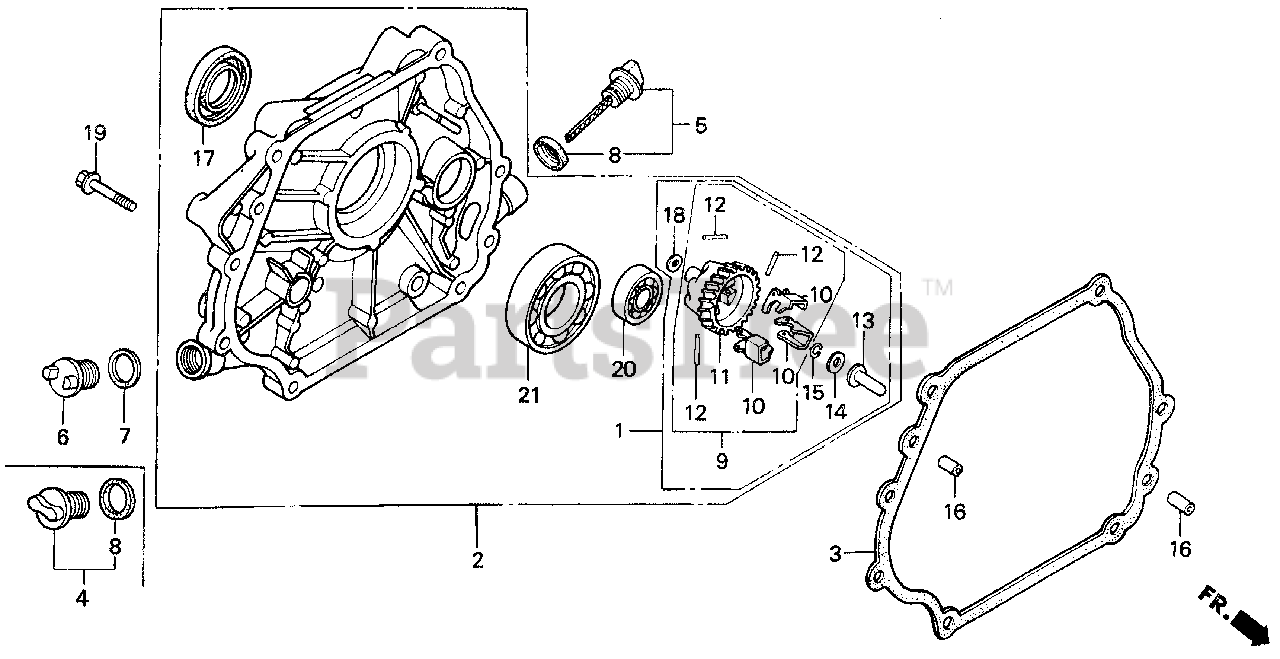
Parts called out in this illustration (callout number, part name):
1	GOVERNOR KIT
2	COVER ASSY., CRANKCASE (Q-TYPE)
3	GASKET, CASE COVER
4	CAP ASSY., OIL FILLER
5	CAP ASSY., OIL FILLER
6	CAP, OIL FILLER
7	GASKET, OIL FILLER CAP
8	GASKET, OIL FILLER CAP
9	GOVERNOR ASSY.
10	WEIGHT, GOVERNOR
11	HOLDER, GOVERNOR WEIGHT
12	PIN, GOVERNOR WEIGHT
13	SLIDER, GOVERNOR
14	WASHER (6X16)
15	CLIP, GOVERNOR HOLDER
16	PIN, DOWEL (8X12)
17	OIL SEAL (35X52X8)
18	WASHER, PLAIN (6MM)
19	BOLT, FLANGE (8X40)
20	BEARING, RADIAL BALL (6202)
21	BEARING, RADIAL BALL (6207)
